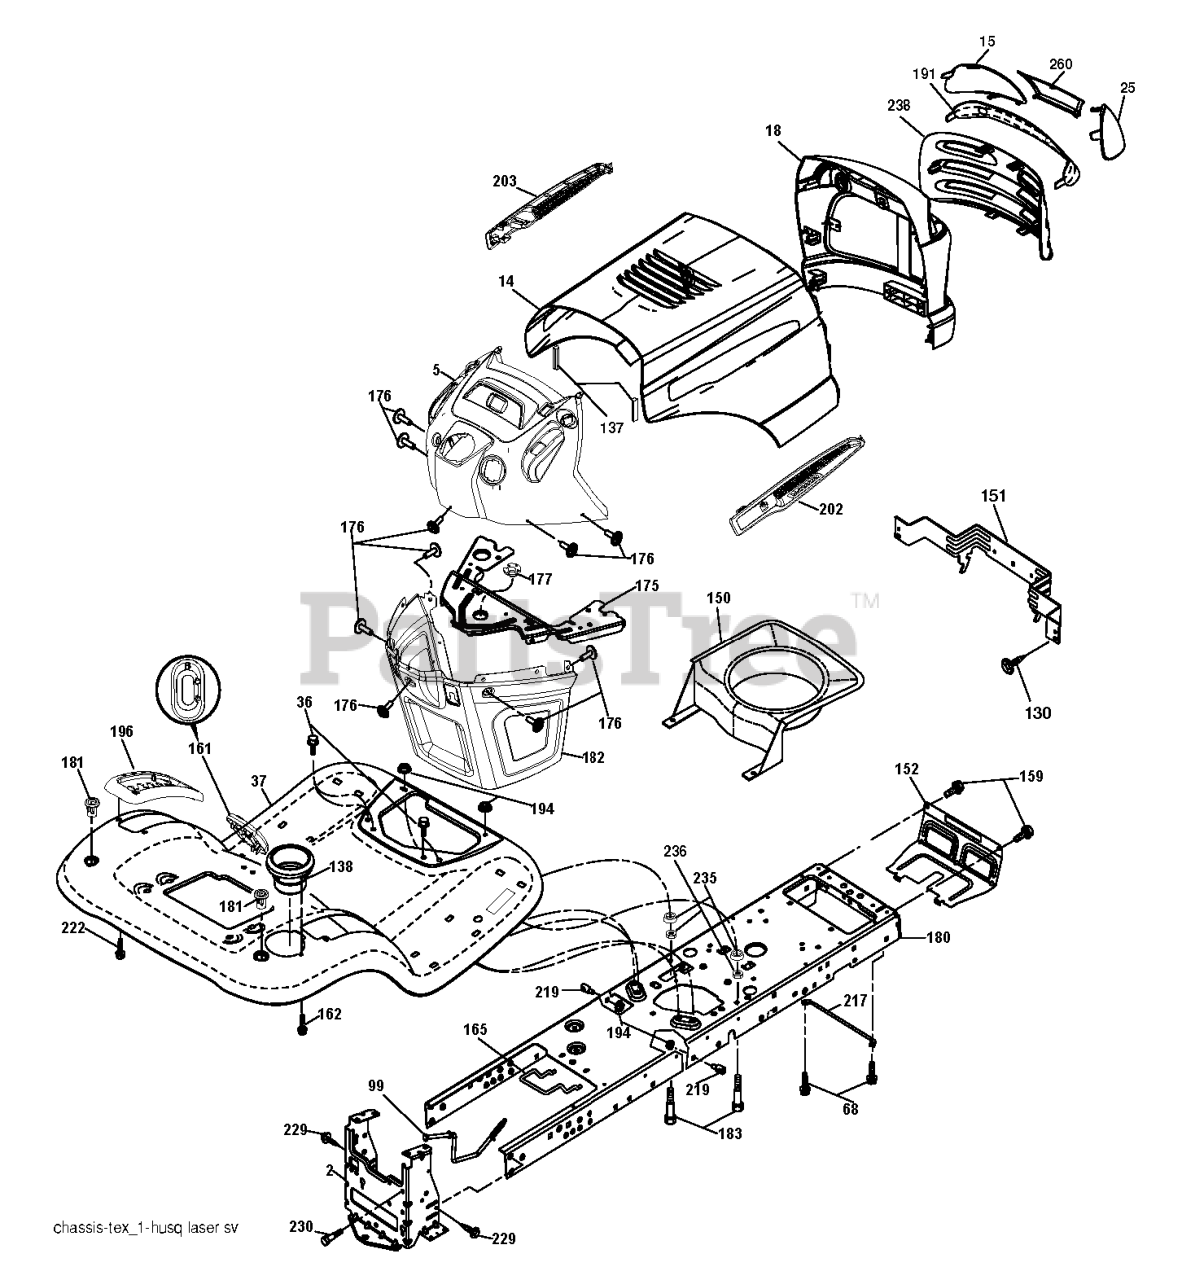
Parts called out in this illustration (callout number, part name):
2	DRAWBAR.1PC.NSTL
14	VENT.HOOD.LASER.III
15	LENS LH
25	LENS LH
36	SCREW 5/16"
37	FEND/FTRST.PCH.CPH.FW
68	Screw 5/16-18 x 1/2 Hex, Self Tapping 5/16-18 x 1/2
99	ROD.ASM.BYPASS.0510.HYDRO.LT
130	SCREW
137	BUMPER.HOOD.LARGE.1.75"
138	CUPHOLDER.TL.TEX.418
151	BRACKET PIVOT
152	SHIELD.BROWNING/DEBRIS
159	SCREW, 3/8-16X3/4
161	WINDOW FUEL
162	SCREW.HI-LO.CONSOLE
165	SUPPORT.TANK.REAR.B/TE
175	CROSSMEMBER.LT
176	SCREW.#10-24X5/8.RN.QU
177	BUSHING STEERING
180	CHASSIS.STAMPING.LT/GT
181	BUSHING.MNT.FEND.CRGO.
182	DASH.LOWER.LT.CCS
183	BOLT.5/16-18X1-1/4 FULL.THREAD
191	INSERT.LENS.REFLECTIVE
194	NUT LOCK HEX FLANGE 5/16-18
196	CONSOLE.ASM.DECK.LIFT.
202	VENT.HOOD.LASER.
203	VENT.HOOD.LASER.
217	ROD PIVOT CHASSIS/HOOD
219	STUD.FASTNER.W/ANTI-ROTATE
222	SCREW.1/4-20X5/8
229	SCREW 3/8-16X1
230	SHOULDER BOLT 5/16-18TT
235	SPACER FENDER
236	NUT.CENTERLOCK.5/16-
260	COVER.LENS.HUSQ.LASER
